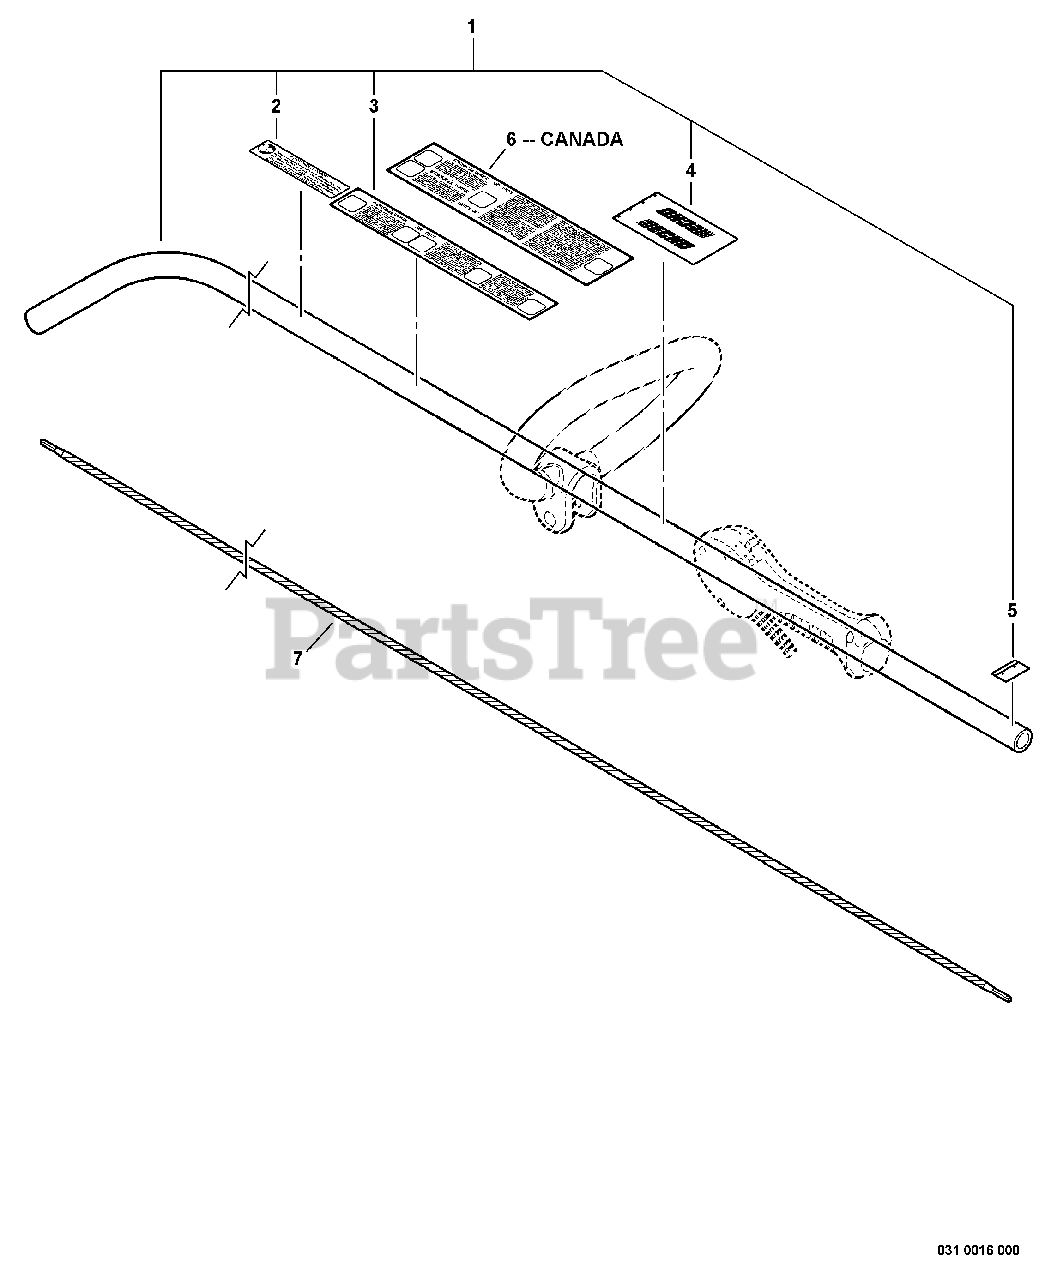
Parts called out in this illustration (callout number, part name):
1	PIPE, MAIN
2	LABEL, CAUTION
3	LABEL, CAUTION
4	LABEL, HANDLE LOCATION
5	LABEL - ALIGNMENT
6	LABEL - CAUTION
7	DRIVESHAFT - FLEXIBLE
